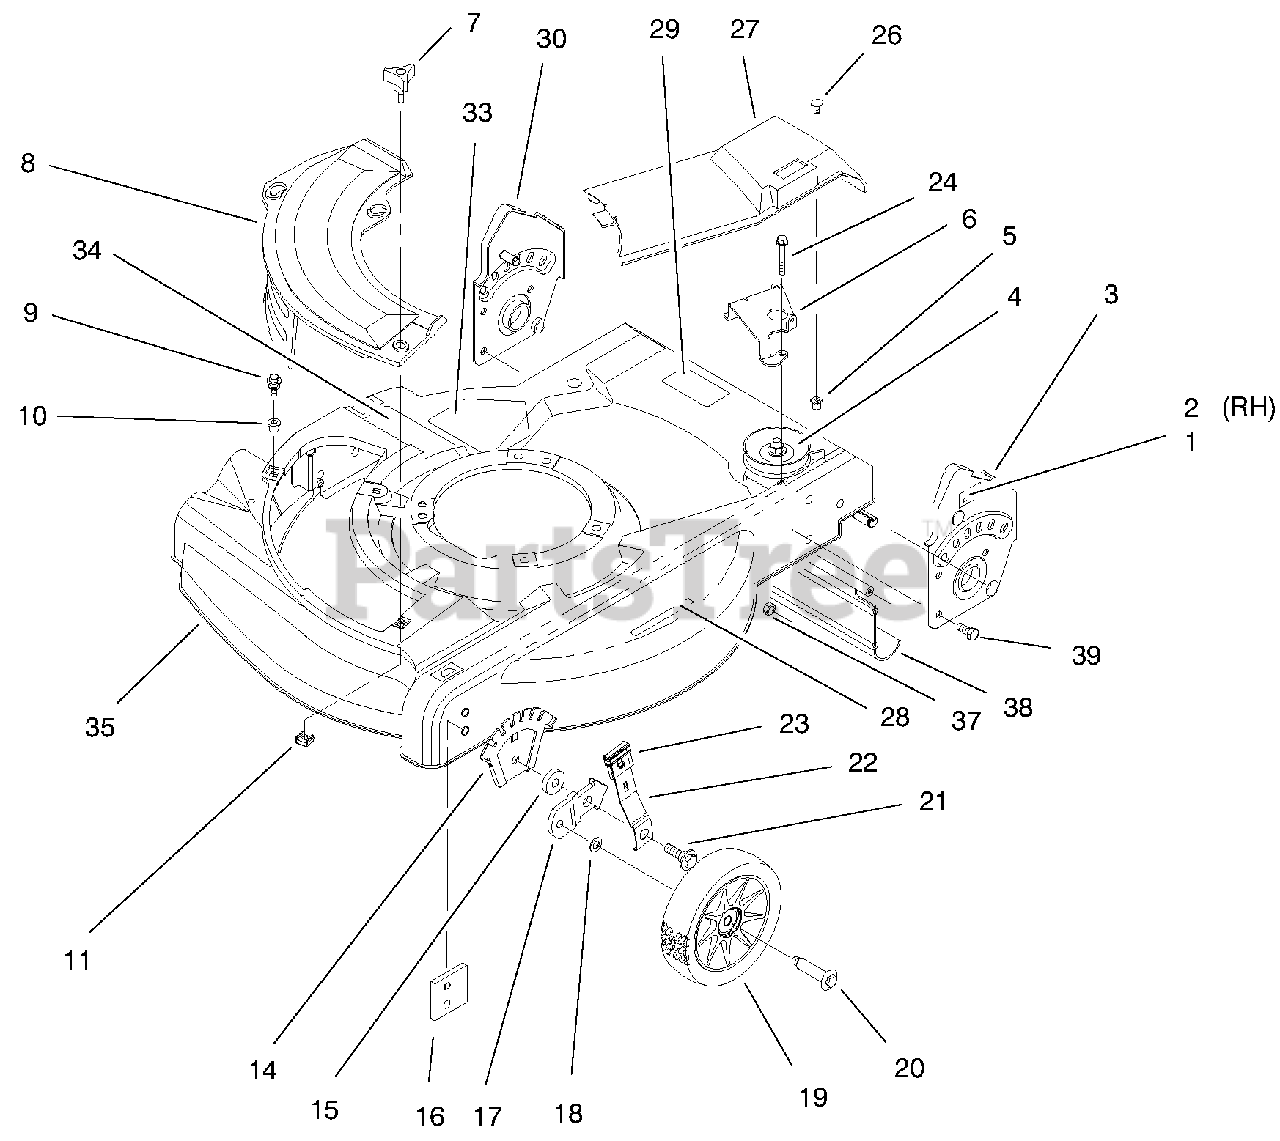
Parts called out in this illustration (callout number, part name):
1	Decal-HOC
2	Decal-HOC
3	ASM-Handle Bracket
4	ASM-Gear Case
5	Grommet
6	Guide-Transmission
7	Knob-Cover Plate
8	Mulch Plate-21"
9	Screw-Sems
10	Grommet-Plastic
11	Nut-Cage
14	Plate-Height Adjust
16	Plate-Baffle
17	Bracket-Wheel Height Adj
19	ASM-Wheel & Tire 6"
20	Bolt-Shoulder 6" Wheel
21	Bolt-Shoulder
22	Spring Arm-Front
23	Knob-Height Adjust
24	Screw-HH
26	Screw-Phil
27	Cover-Drive
28	Decal-Warning
30	ASM-Handle Bracket
32	Plate-Cover
33	Decal-Danger
34	Decal-Discharge
35	ASM-Housing & Baffle
37	Nut-Lock
38	Shield-Trailing
39	Screw-HH
